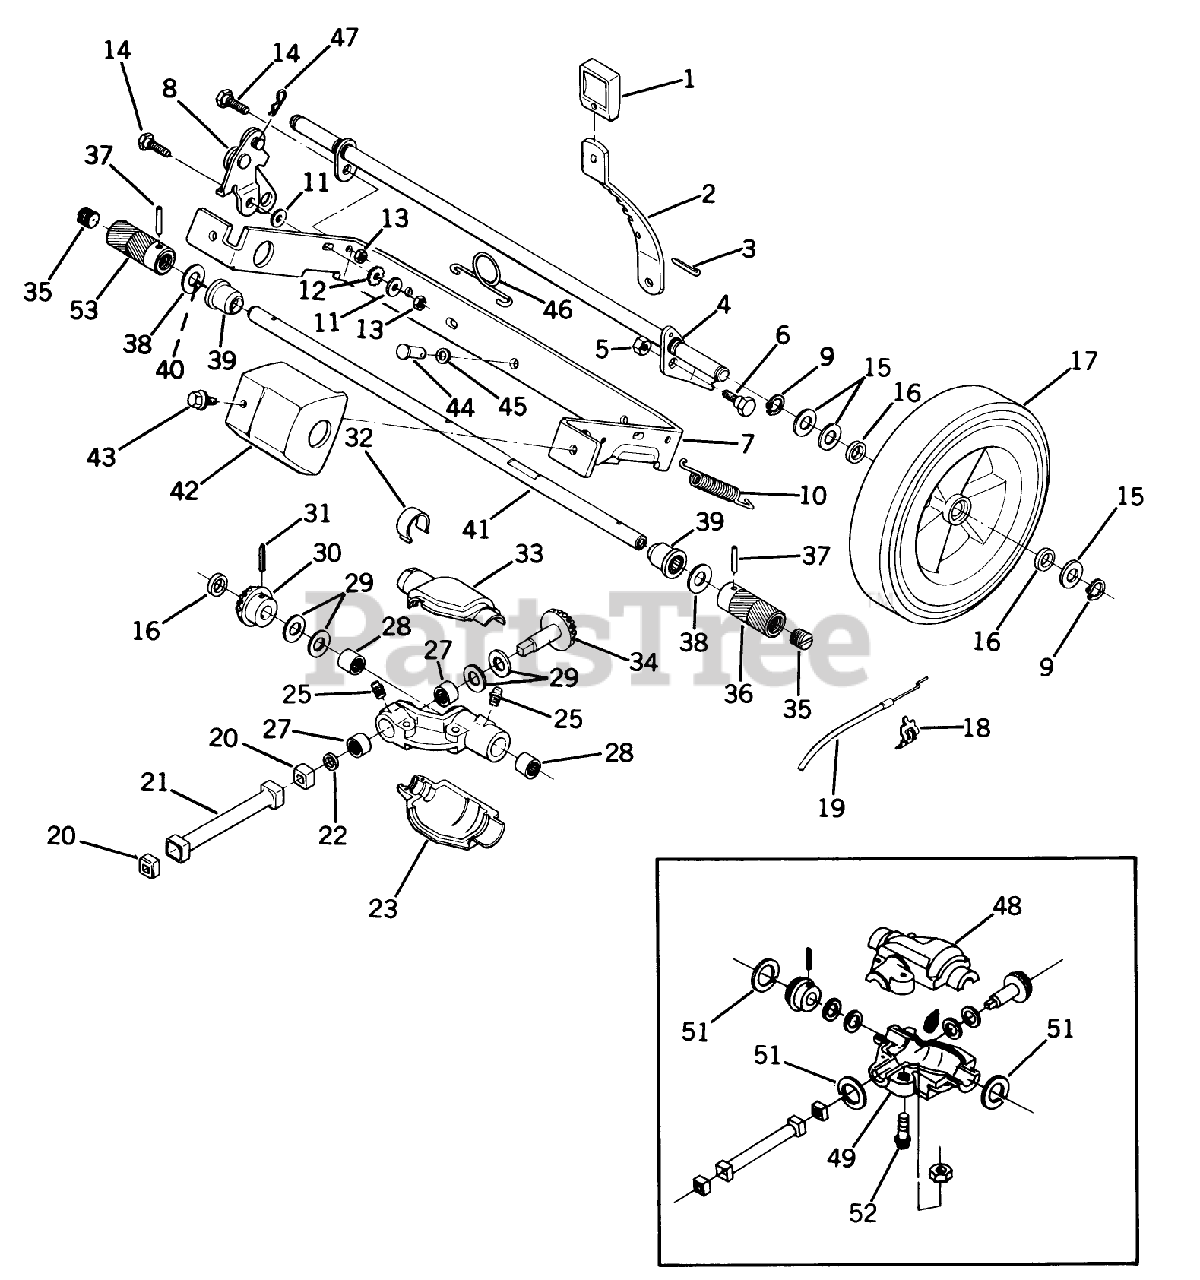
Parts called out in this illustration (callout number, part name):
1	KNOB
2	LEVER
5	LOCKNUT E
6	BOLT RB&W
9	RET RING
10	SPRING
11	WASHER S
13	STOP NUT
14	BOLT RB&W
15	SPACER
16	WASHER
20	BUSHING
22	O Ring
25	**FITTING LINCOLN
27	NEEDLE BEARING
29	THRUST WASHER
31	ROLL PIN
33	GEAR COVER UPPER
35	GREASE PLUG
37	PIN
40	BEARING AY F
41	DRIVE SHFT TAG AY
42	GUARD
44	PIN
45	WASHER SPRING LAR
46	SPRING N.A.S
50	ZERK FITTING
